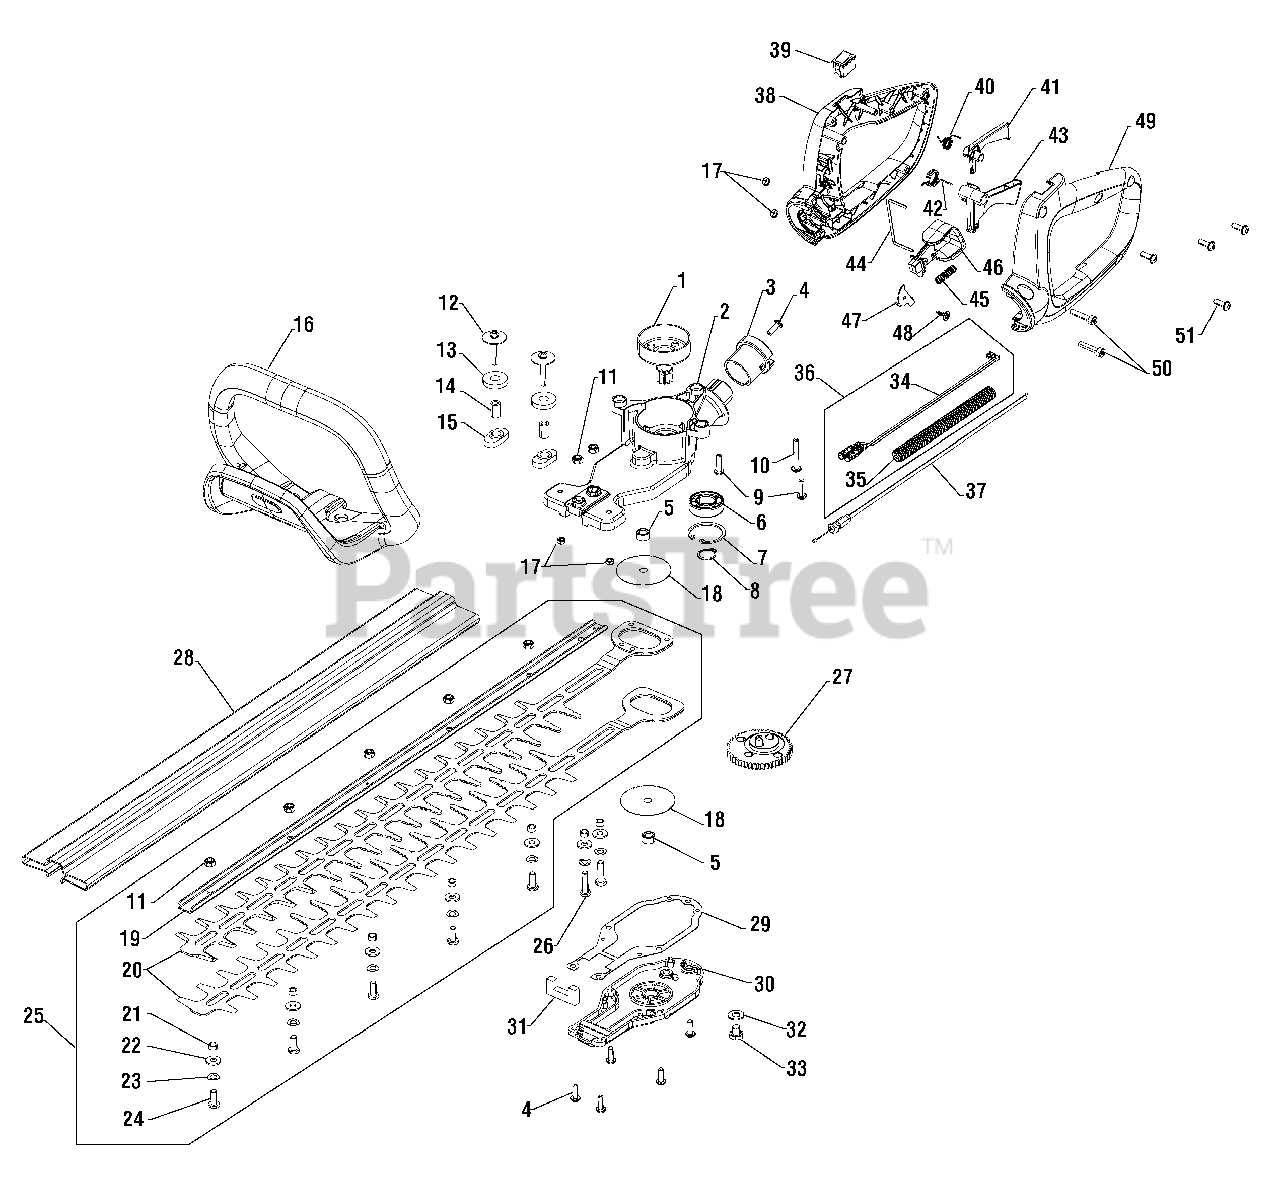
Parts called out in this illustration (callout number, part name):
1	Clutch Drum
2	Kit - Gear Box
3	Handle Bush
6	Ball Bearing 6003 C3
7	C Ring
8	C Ring
11	Nut
13	Shock Absorption, Upper
15	Shock Absorption, Lower
16	Handle Front
19	Blade Support
23	Wave Washer
24	Screw
25	Blade Assembly
27	Kit - Gear Assembly
28	Blade Cover
30	Cover, Gear Box
34	Coil Wire
35	Flexible Conduit
36	Ignition Cable Assembly
37	Throttle Cable
38	Handle, Right
40	Spring, Release
41	Trigger, Release
42	Spring, Throttle
43	Trigger, Throttle
44	Rotate Lock, Linkage
45	Spring, Rotate Release
46	Bar Rotate, Release
47	Plate, Cable
49	Handle, Left
